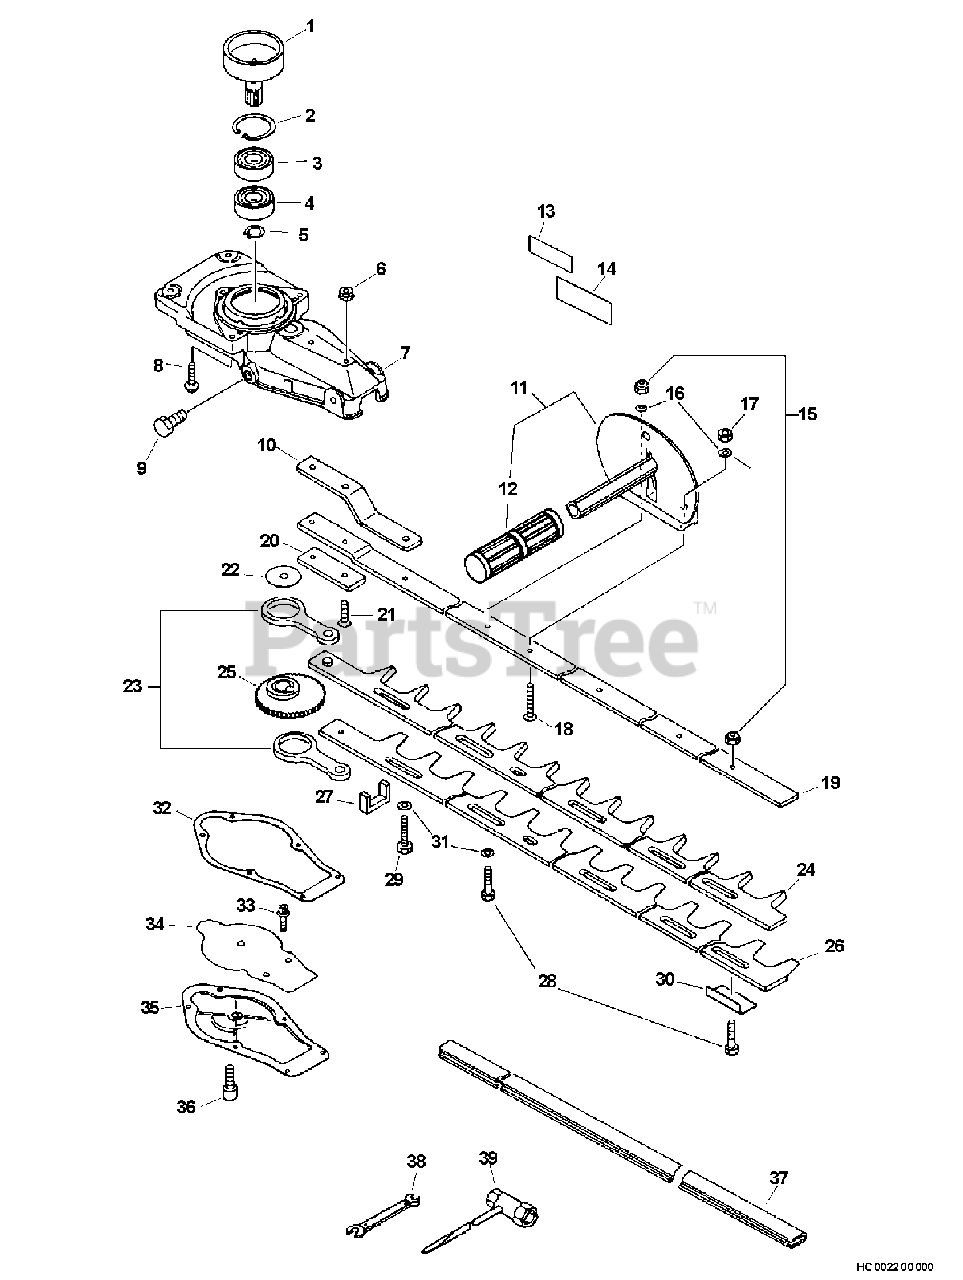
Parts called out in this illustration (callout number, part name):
1	DRUM, CLUTCH
2	RING, SNAP 35
3	BEARING, BALL 6202
4	BEARING, BALL 6202
5	RING, SNAP 14
6	NUT, HEX M6
7	CASE, GEAR
8	BOLT 5×25
9	BOLT 8×8 SP
10	PLATE, ANGLE
11	BRACKET ASSY
13	LABEL, CAUTION - ISO
14	LABEL, CAUTION
16	WASHER 5.5×18×1
18	SCREW 6×30
19	SUPPORT, BLADE
20	PLATE, EYE
21	SCREW 6×25
23	ROD, CONNECTING
24	BLADE, TRIMMER - UPPER
26	BLADE, TRIMMER - LOWER
28	BOLT, CUTTER
29	BOLT 6×35
30	INSULATOR
31	WASHER 6.5×15.5×0.6
32	GASKET, GEAR CASE
33	BOLT 5×12
34	PLATE, GEAR CASE
35	COVER, GEAR CASE
36	BOLT 4×12
37	SCABBARD
38	SPANNER 8×10
39	T-WRENCH 13×19×180
